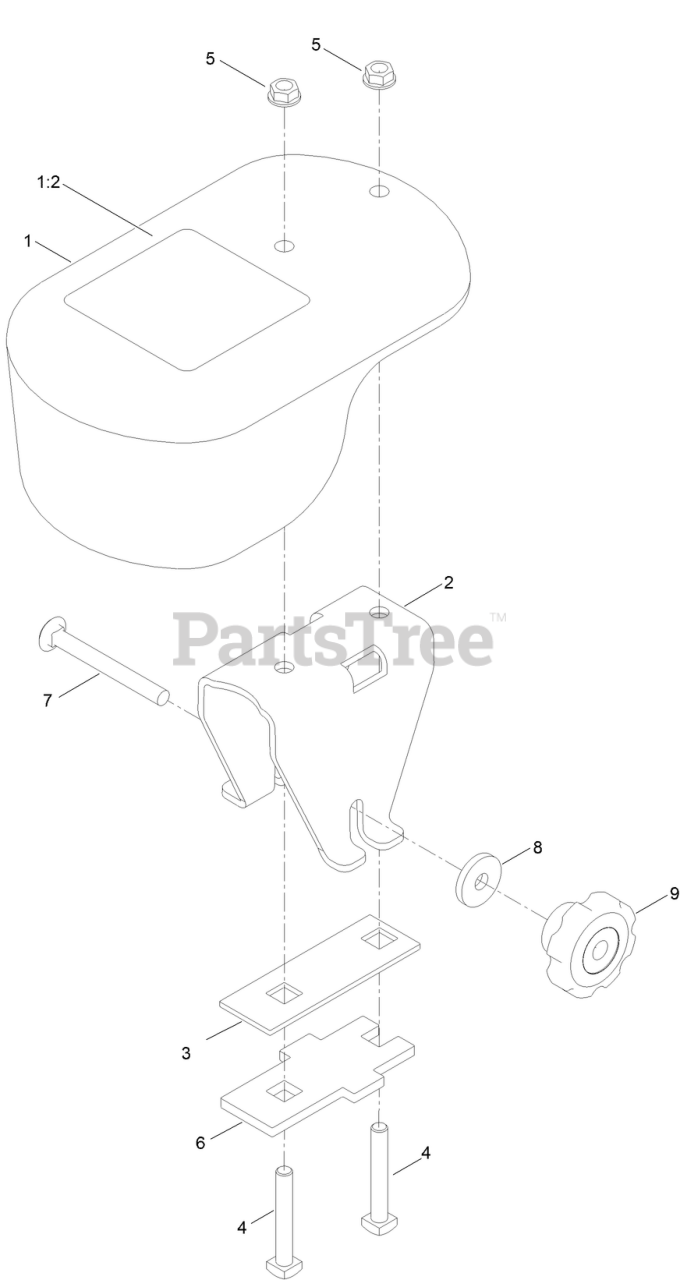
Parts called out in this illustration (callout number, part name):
1	WEIGHT WITH DECAL ASM
1:2	DECAL-WARNING, TRACTION
2	CHANNEL-MOUNT, WEIGHT
3	PLATE-BRACKET, WEIGHT
4	BOLT-SQH
5	NUT-HHF, WHIZ
6	PLATE-BRACKET, WEIGHT
7	SCREW-CARR
8	WASHER-BACKUP
